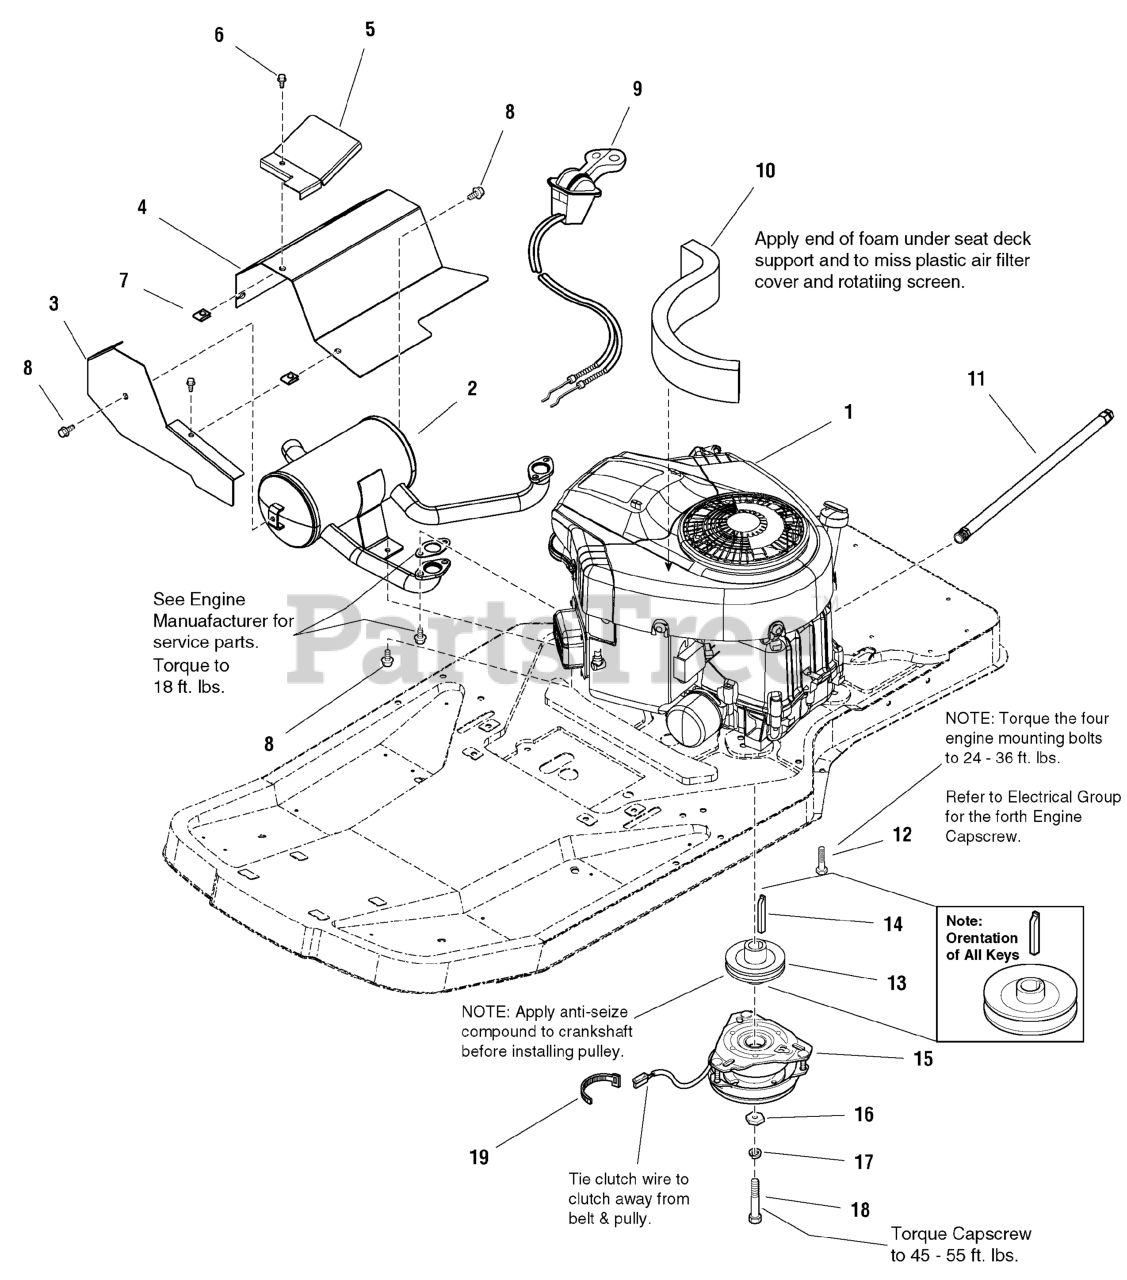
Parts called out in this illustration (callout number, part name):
1	ENGINE, 22HP, Briggs & Stratton
2	MUFFLER
3	SHIELD, Heat, Muffler Side
4	SHIELD, Heat, Muffler Top
5	SHIELD, Heat, Throttle
6	CAPSCREW, Hex Flange, Whiz Lock, 1/4-20 x 5/8
7	NUT, Speed Lug Type, 1/4-20
8	SCREW, Hex Washer Head, Taptite, 5/16-18 x 1/2
9	CONTROL, Throttle
10	SEAL, Foam, 1 x 2-1/2, 12" LG Curved
11	HOSE, Oil Drain
12	CAPSCREW, Hex Head, Taptite, 3/8-16 x 1-1/2 (For 1692768)
13	PULLEY, 3.74 OD x 1.003 ID x 1.88 LG
14	KEY, Hi-Pro, 1/4 x 2-1/2
15	CLUTCH, Electric Ogura
16	WASHER, Hex
17	LOCKWASHER, Spring, 7/16
18	CAPSCREW, Hex Head Cap, 7/16-20 x 2-3/4, GR5, Black
19	TIE, Self Locking, 3-5/8 LG
